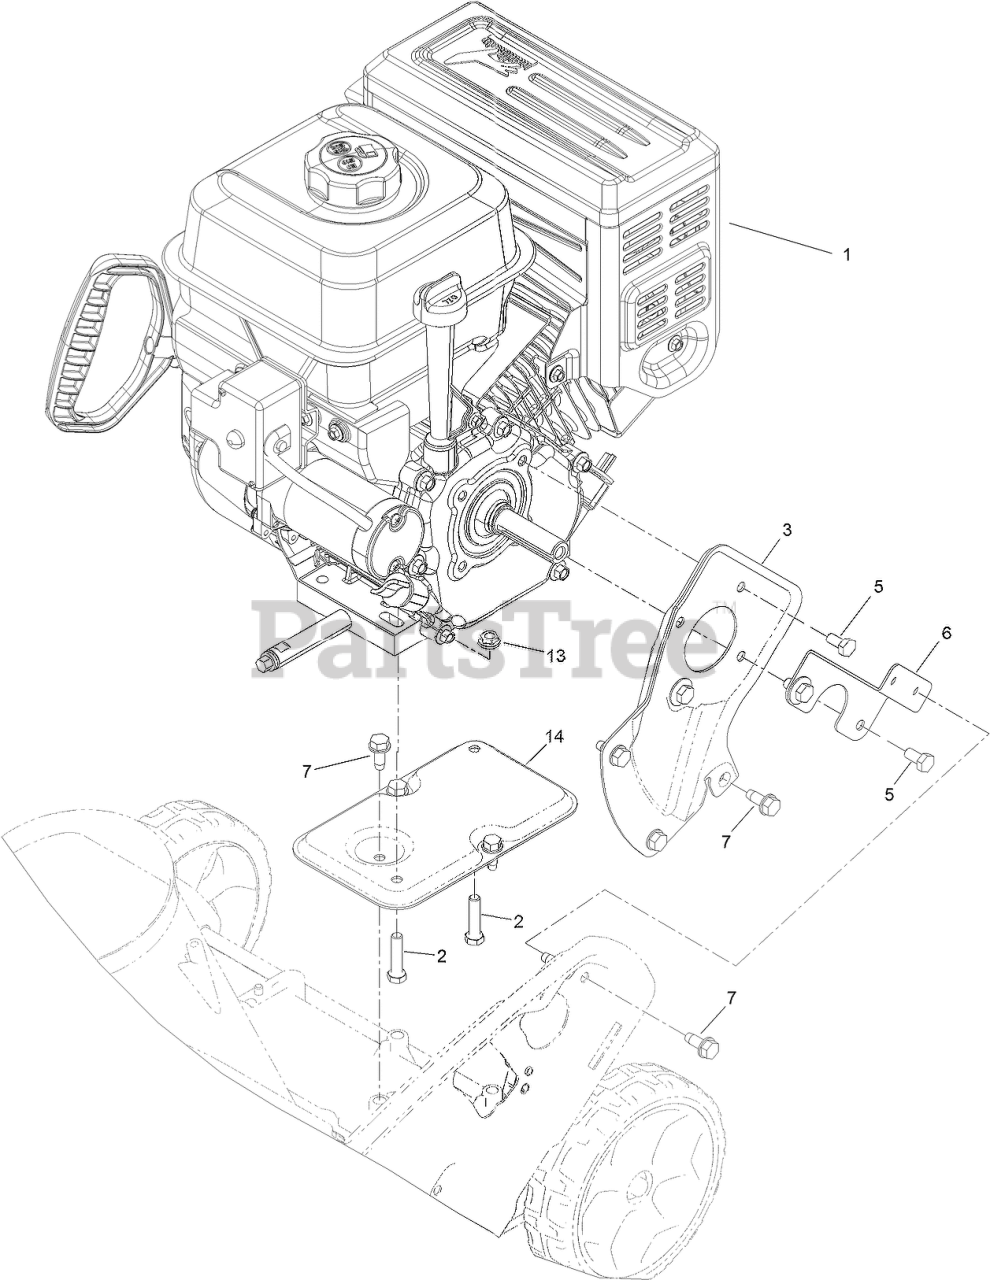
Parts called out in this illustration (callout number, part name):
1	ENGINE - G210FS-4
2	SCREW-HH
3	PLATE-ENGINE, PTO
5	BOLT
6	SUPPORT-ENGINE, SIDE
7	SCREW-THD ROLL, HWH
13	NUT-HF
14	SUPPORT-ENGINE
